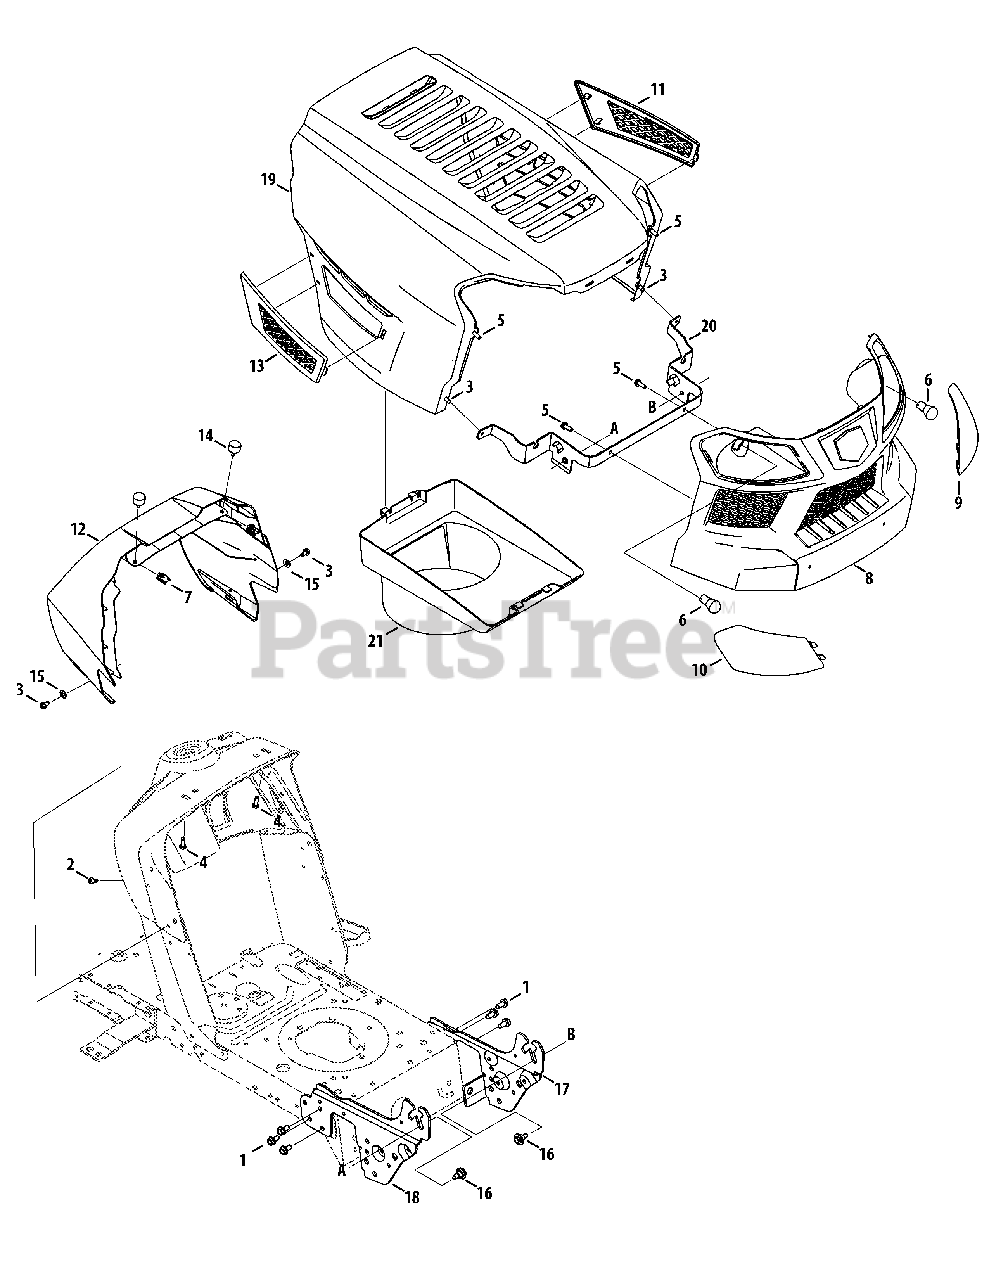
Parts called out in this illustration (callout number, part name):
1	Screw, 5/16-18 x .750
2	Self-Tap Screw, 1/4-20 x .5
3	Hex Washer Screw, 1/4-20 x .500
4	Self-Tap Screw, 1/4-20 x .75
5	Plastic Screw, 1/4-10 x .75
6	Headlight Bulb
7	U-Clip Nut
8	CPX Grill
9	Grill Lens, LH
10	Grill Lens, RH
11	Side Cover, LH
12	Dash Collar
13	Side Cover, RH
14	Bumper, .62 DIA X .50
15	Flat Washer, .25 X.630 X.0515
16	Shoulder Screw, .43 x .29, 5/16-18
17	Pivot Support Bracket, LH
18	Pivot Support Bracket, RH
19	Hood
20	Grill Pivot Bracket
21	Plenum
